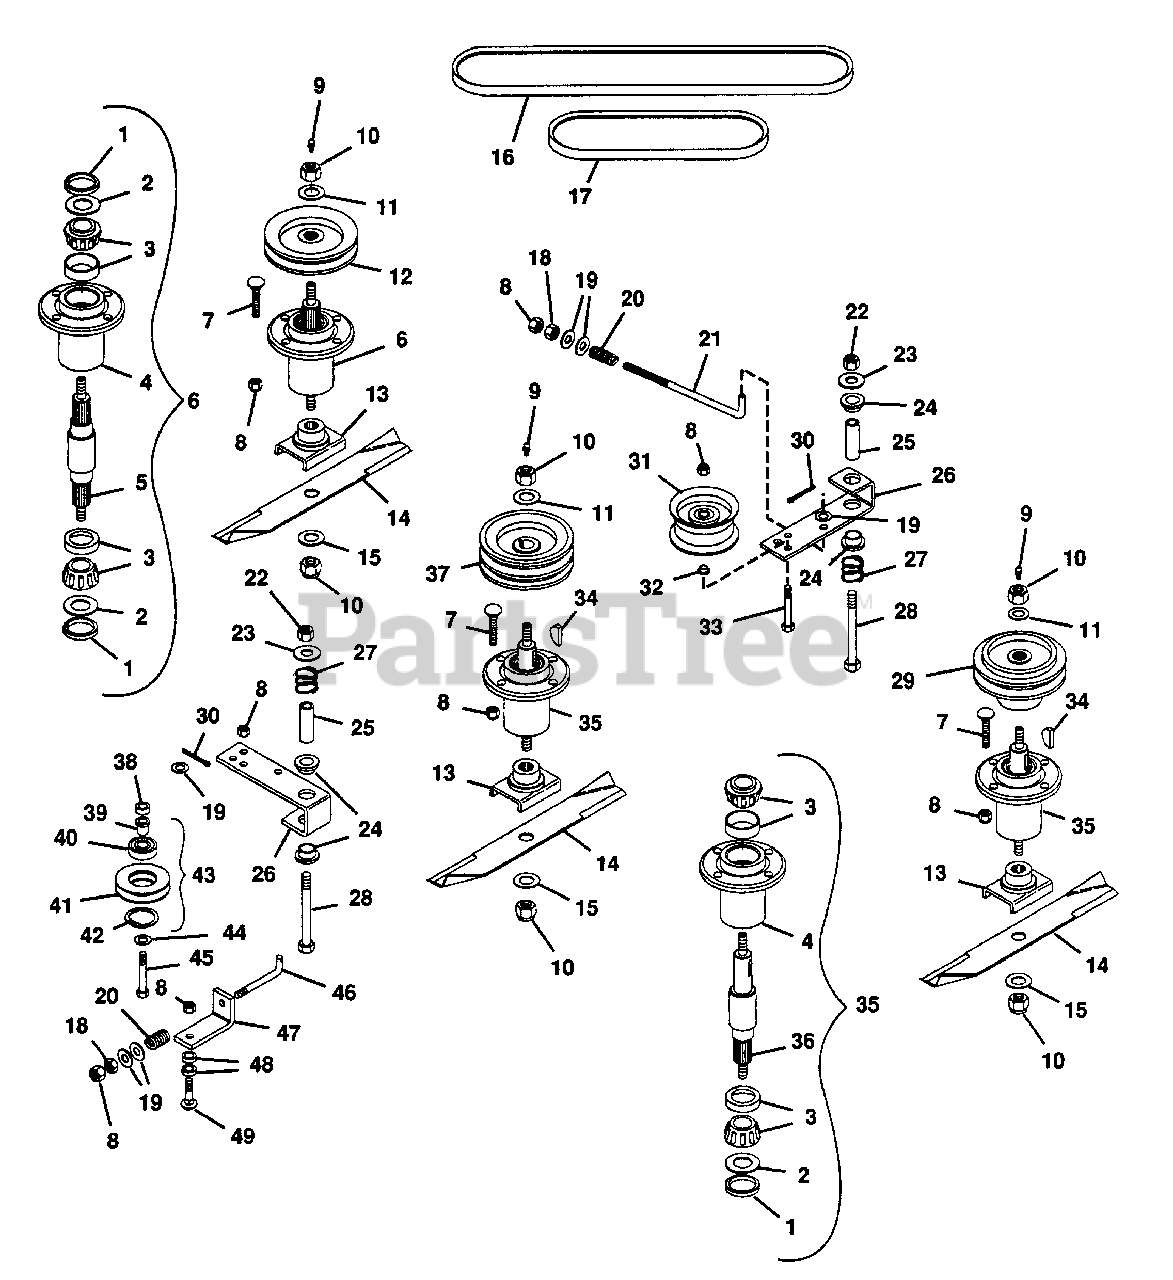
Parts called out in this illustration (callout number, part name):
1	Seal, Steel(in 34605)
1	Seal, Steel(in 21306)
2	Washer, Flat .975x1.970x.030(in 34605)
2	Washer, Flat .975x1.970x.030(in 21306)
3	Assembly, Bearing
4	Housing, Bearing
5	Shaft, Spindle
6	Assembly, Spindle
7	Bolt, 3/8-16x1.375 Rd Hd Sq Nk
8	Nut, Lock 3/8-16
9	Fitting, Lube 1/8
10	Nut, Lock 5/8-11
11	Washer, Flat .687x1.312x.122
12	Pulley
13	Weldment, Blade Cradle
14	Blade
15	Washer, Flat .656x1.312x.095
16	Belt, V
17	Belt, V
18	Nut, Hex 3/8-24
19	Washer, Flat .406x.812x.065
20	Spring, Comp. 1x.78x338 Lb/N
21	Rod, Idler
22	Nut, Lock 1/2-13
23	Washer, Flat .531x1.250x.100
24	Bush., Flg. .764x1.47x.560 Ny.
25	Bush., St. .560x.750x2.44 Stl.
26	Arm, Idler Pivot
27	Spring, Comp. 1x.80x36 Lb/N
28	Bolt, Hex 1/2-13x3.25
29	Sheave, Spindle
30	Pin, Cotter .09x.75
31	Pulley, Idler
32	Bush., Flg. .406x.880x.270 Brz.
33	Bolt, Hex 3/8-16x2.25
34	Key, Woodruff .250x1 Hard #15
35	Assembly, Spindle
36	Shaft, Spindle
37	Sheave, Mower Spindle
38	Bush., St. .406x.625x.480 Stl.
39	Bush., Flg. .391x1.00x.760 Stl.
40	Bearing, Ball
41	Sheave, Idler
42	Ring, Retaining
43	Assembly, Idler Sheave
44	Washer, Flat .375x1.125x.065
45	Bolt, Hex 3/8-16x2.00
46	Rod, Idler
47	Bracket, Belt Tensioner
48	Bush., St. .391x1.00x.250 Stl.
49	Bolt, 3/8-16x1.75 Rd Hd Sq Nk
